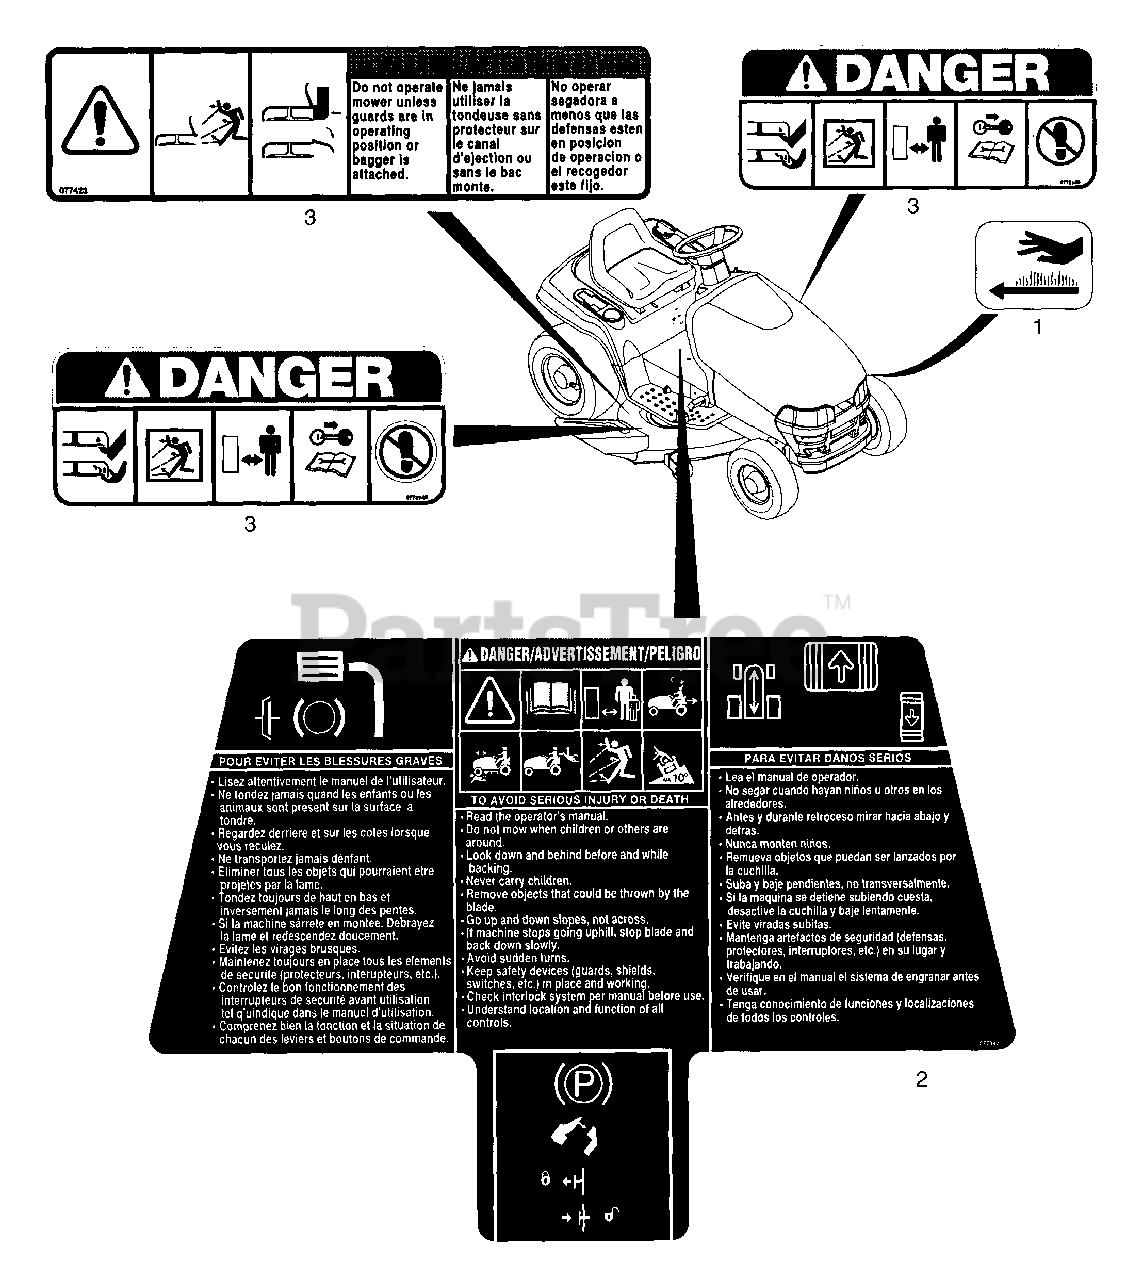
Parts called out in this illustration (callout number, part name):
1	Decal-Hot Surface
2	Decal-Operating Instructions
3	Decal Set-Mower Pan
